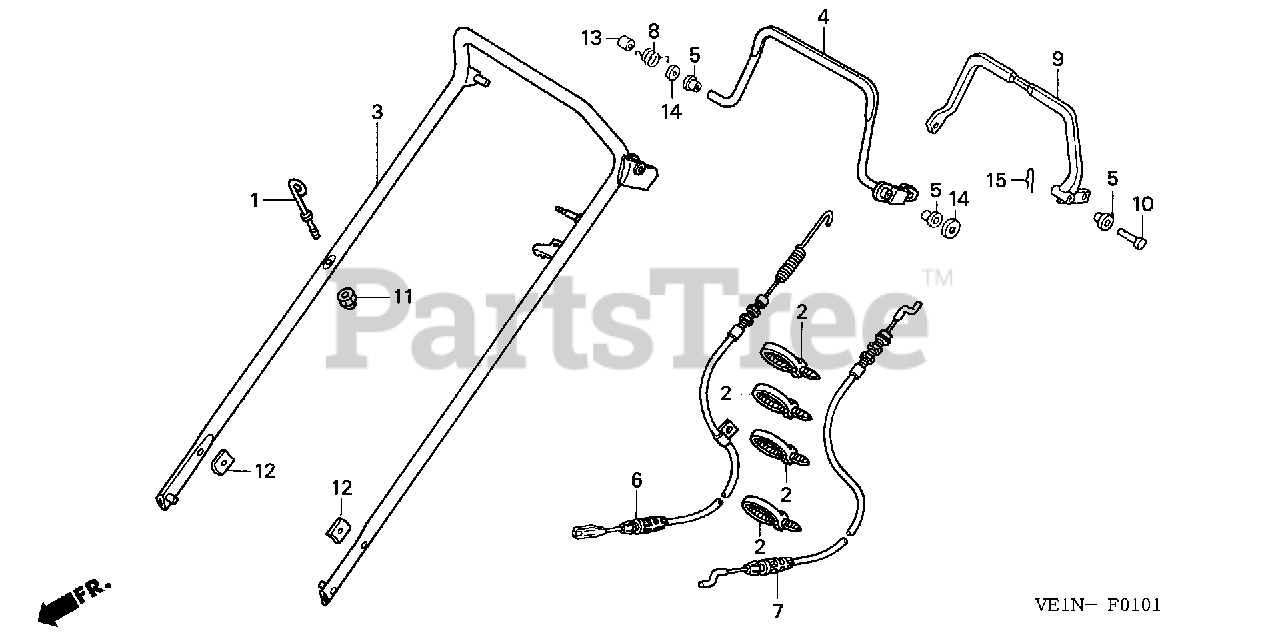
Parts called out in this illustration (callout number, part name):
1	GUIDE, ROPE
2	TIE, CABLE (157.5MM)
3	PIPE, HANDLE *NH105* (MAT BLACK)
4	LEVER, CLUTCH
5	BUSH, CLUTCH LEVER
6	CABLE, CLUTCH
7	CABLE, BRAKE
8	SPRING, R. STOP RETURN
9	LEVER, BRAKE *NH105* (MAT BLACK)
10	PIN, CLUTCH LEVER
11	NUT, NYLON LOCK (6MM)
12	WASHER, FRAME JOINT
13	COLLAR (8X11X13.5)
14	WASHER, PLAIN (8MM)
15	PIN, LOCK (8MM)
